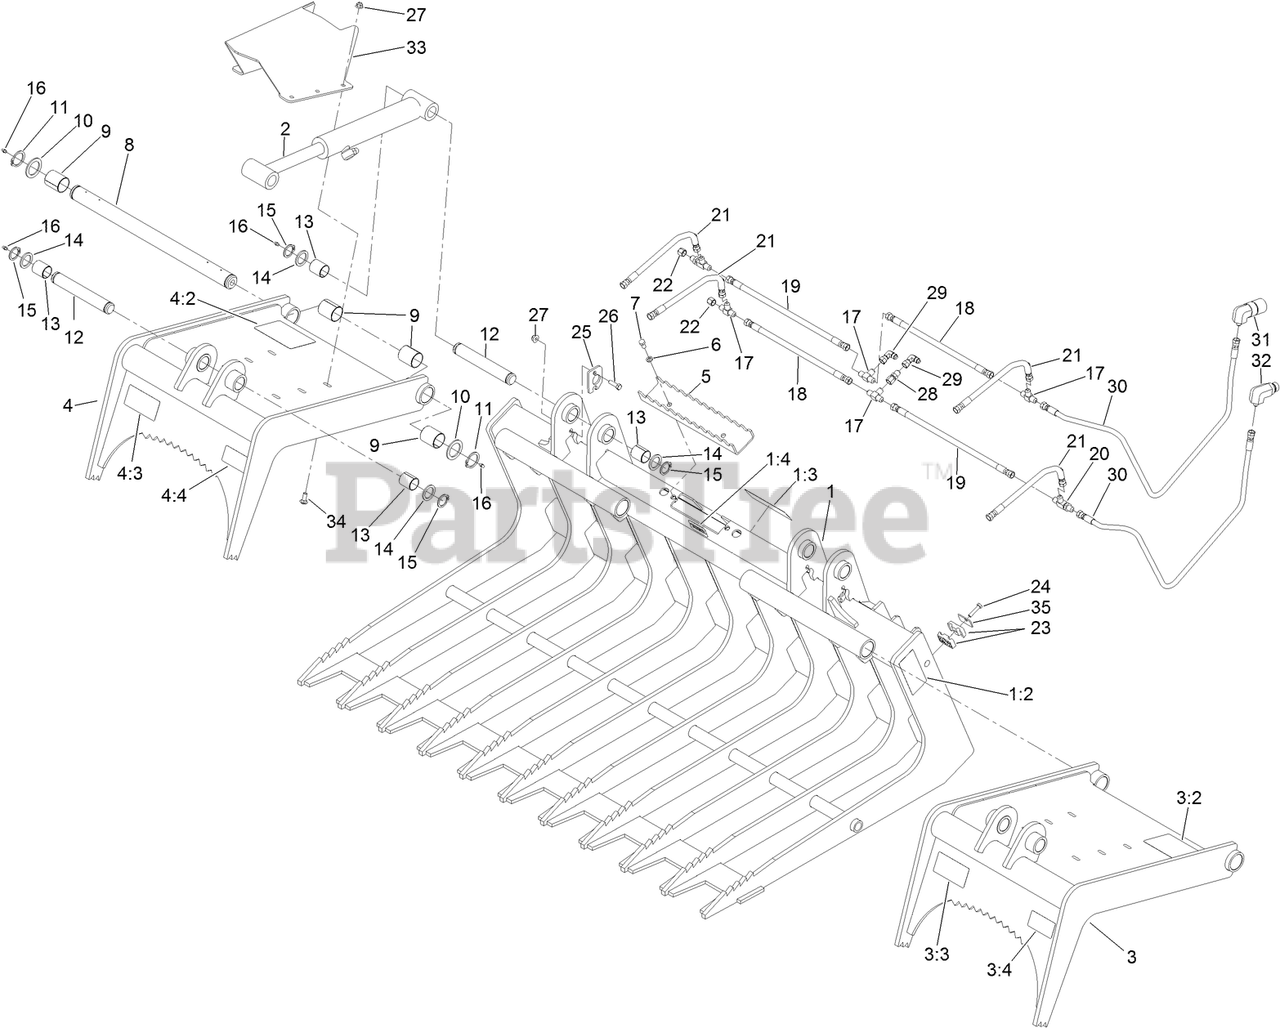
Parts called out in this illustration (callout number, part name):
1	FRAME ASM
1:2	DECAL-WARNING
1:3	DECAL-CAPACITY
1:4	DECAL
2	HYDRAULIC CYLINDER ASM
3	LH JAW ASM
3:2	DECAL-DANGER, GRAPPLE
3:3	DECAL-WARNING, PINCH POINT
3:4	DECAL-DANGER
4	RH JAW ASM
4:2	DECAL-DANGER, GRAPPLE
4:3	DECAL-WARNING, PINCH POINT
4:4	DECAL-DANGER
5	STEP-GRAPPLE
6	WASHER-LOCK
7	SCREW-HH
8	PIN-HINGE
9	BUSHING
10	WASHER
11	RING-SNAP, EXTERNAL
12	PIN-PIVOT
13	BUSHING
14	WASHER-STEERING
15	RING-RETAINING, EXTERNAL
16	FITTING-ZERK
17	FITTING-TEE
18	HOSE-HYD
19	HOSE-HYD
20	FITTING-TEE
21	HOSE-HYD
23	CLAMP-TUBE
24	SCREW-HH
25	RETAINER CLIP-HOSE
26	SCREW-HH
27	NUT-HF, NI
28	FITTING-RESTRICTOR
29	ELBOW-SWIVEL, 90 DEG
30	HOSE-HYD
31	FITTING-ELBOW
32	FITTING-ELBOW
33	GUARD-CYLINDER
34	SCREW-HH
35	COVERPLATE
